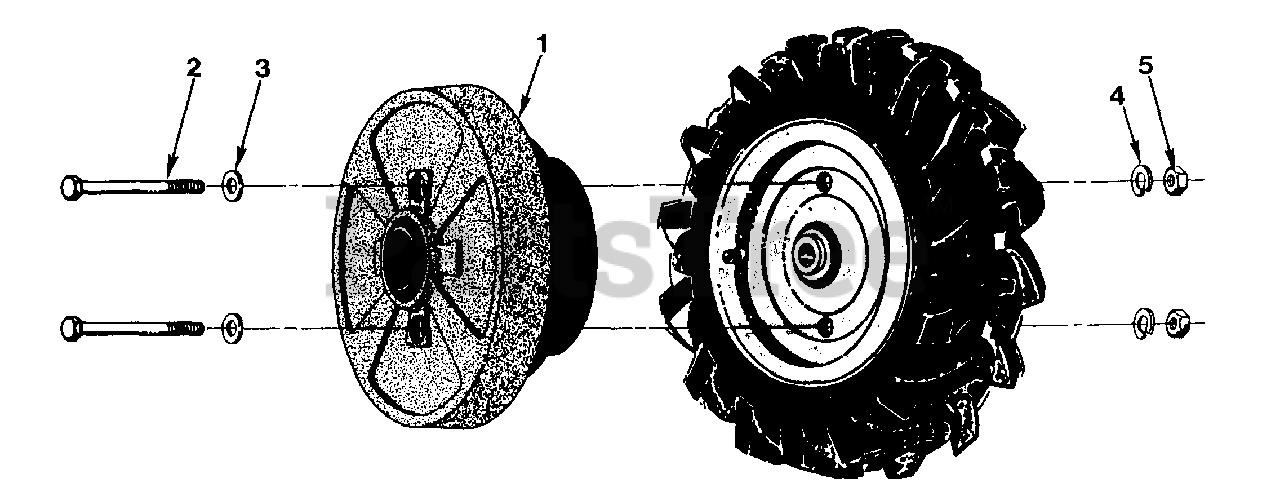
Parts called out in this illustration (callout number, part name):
1	Shell-wheel weight
2	Screw-hex hd., 3/8-16 x 6"
3	Washer-flat, 3/8"
4	Lockwasher-spring, 3/8"
5	Nut-hex, 3/8"-16
